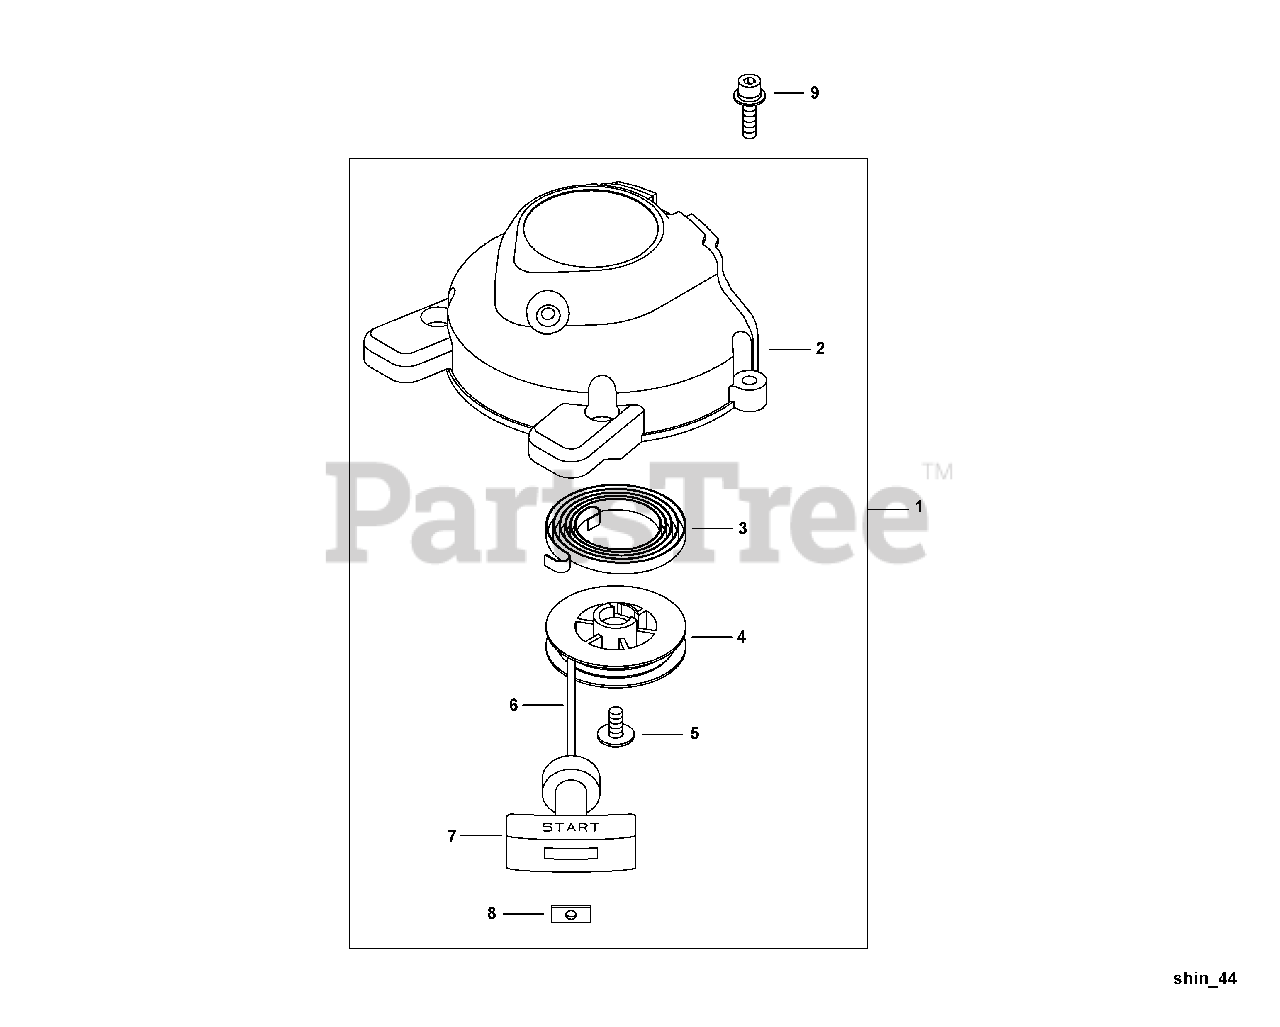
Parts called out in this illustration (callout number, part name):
1	STARTER ASSY
2	CASE, STARTER
3	SPRING, REWIND
4	REEL, ROPE
5	SCREW - 5
6	ROPE, STARTER
7	GRIP, STARTER
8	RETAINER, ROPE
9	SCREW - 5X20
